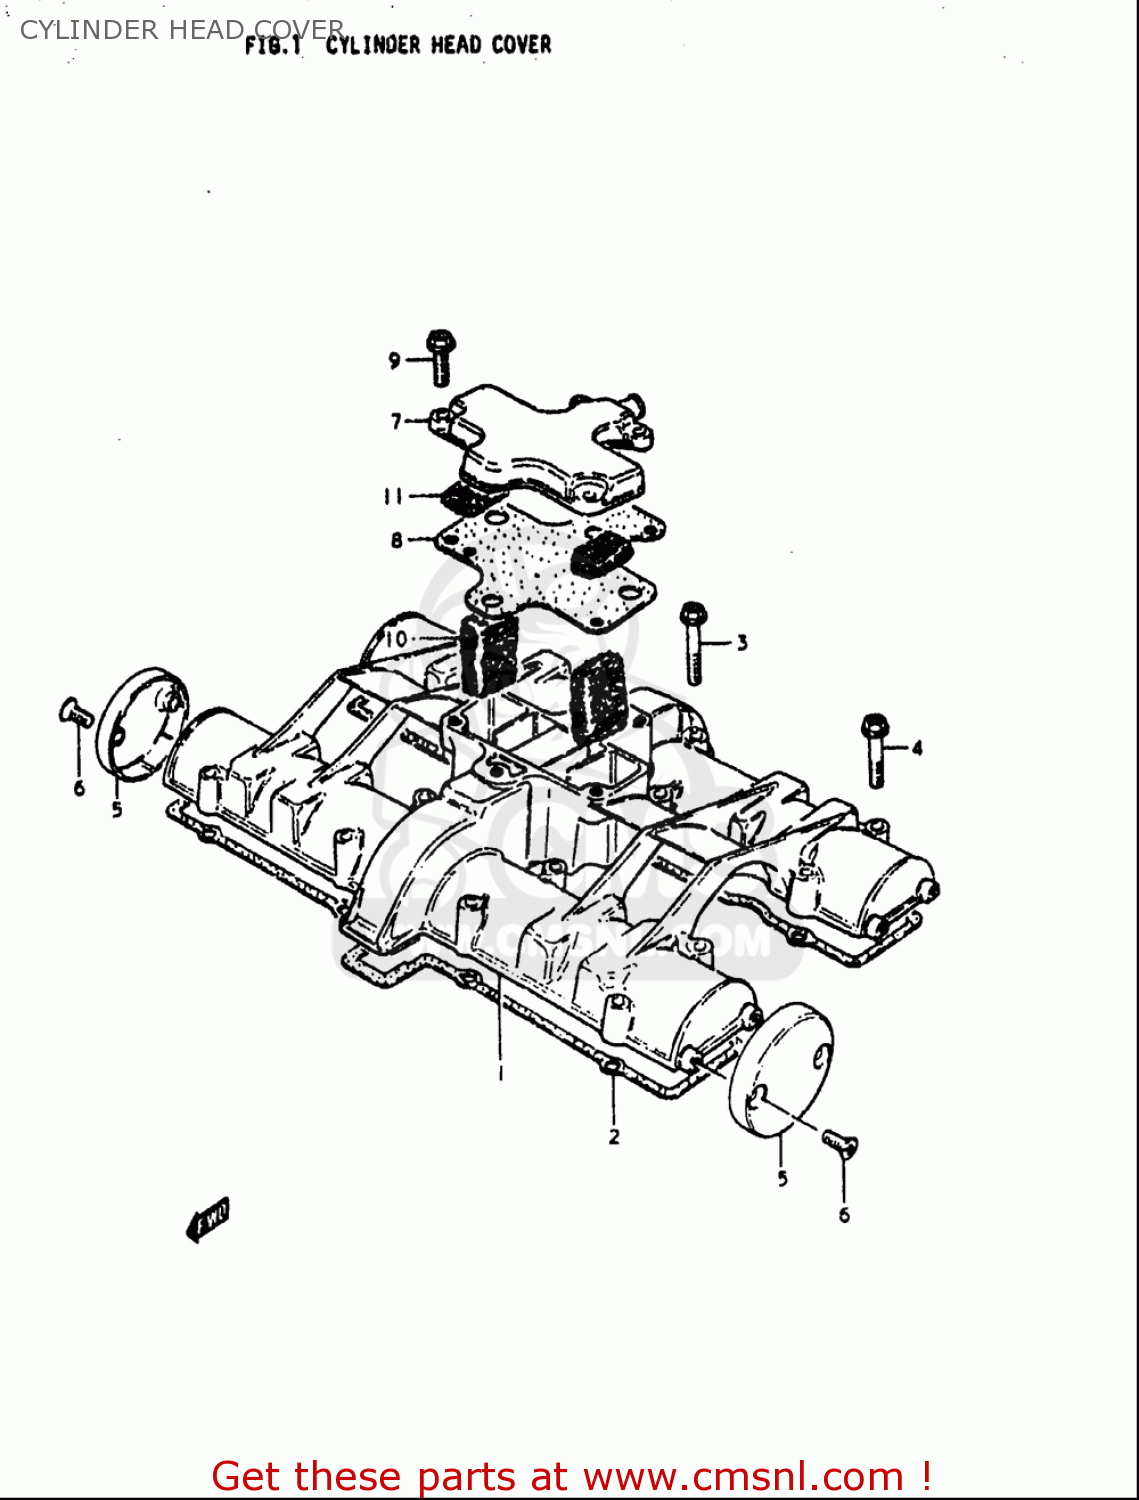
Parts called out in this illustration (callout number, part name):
2	GASKET,CYLINDER HEAD COVER (NAS)
3	BOLT
4	BOLT
5	CAP,CYLINDER HEAD COVER
6	SCREW
7	COVER,BREATHER
8	GASKET,BREATHER COVER (NAS)
9	BOLT
10	SEPARATOR,OIL BREATHER
11	SEPARATOR,OIL BREATHER
